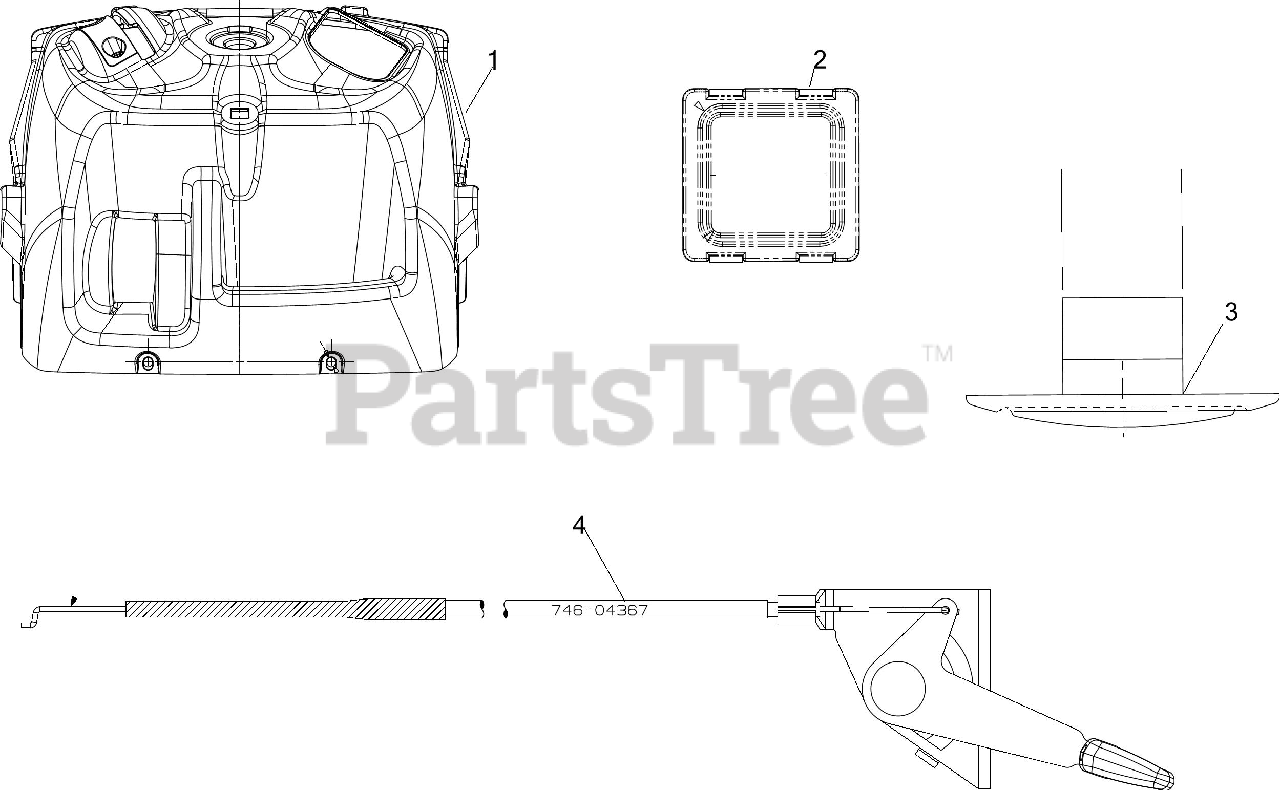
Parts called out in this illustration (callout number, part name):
1	UPPER DASH
2	AMMETER DASH PLUG
3	CHOKE PLUG
4	THROTTLE CABLE 28 X 1.1"
